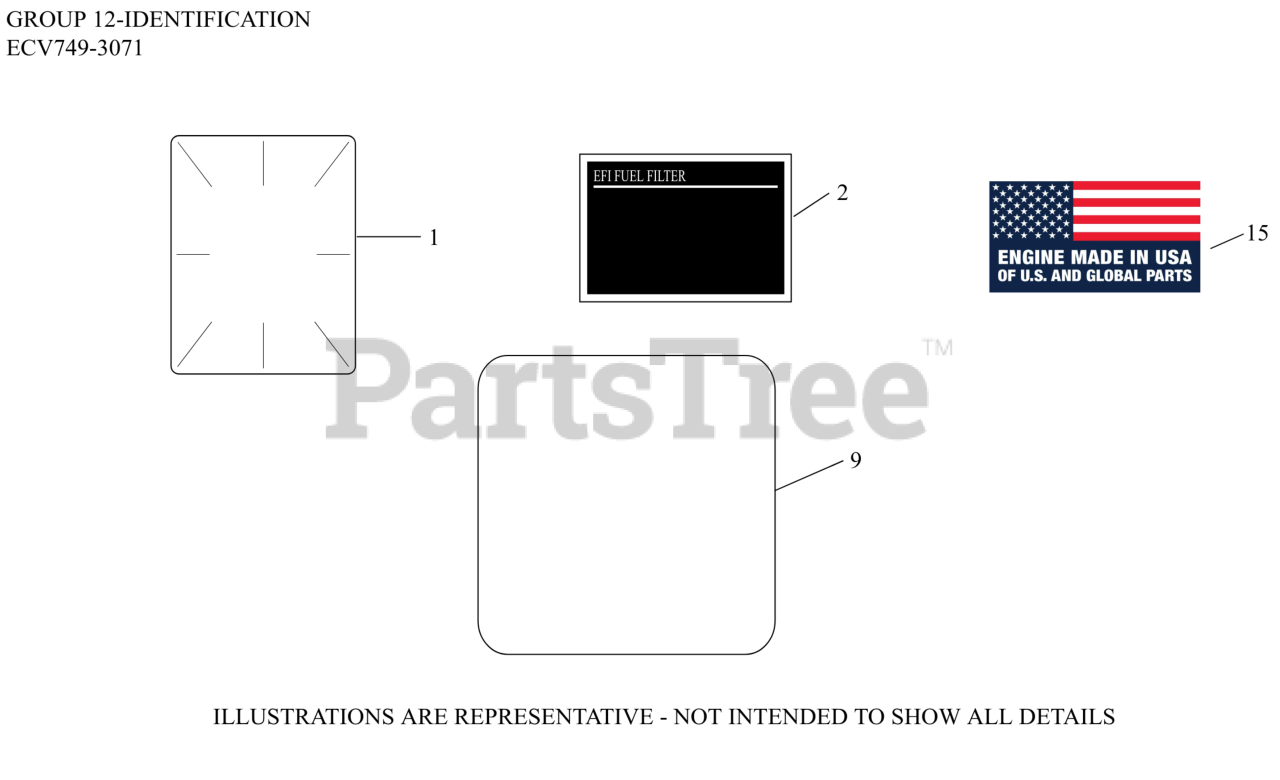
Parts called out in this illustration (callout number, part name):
1	LABEL, CLEAR LAMINATION
2	LABEL, EFI FUEL FILTER
9	DECAL HDAC, ECV749/747cc
15	DECAL, USA
